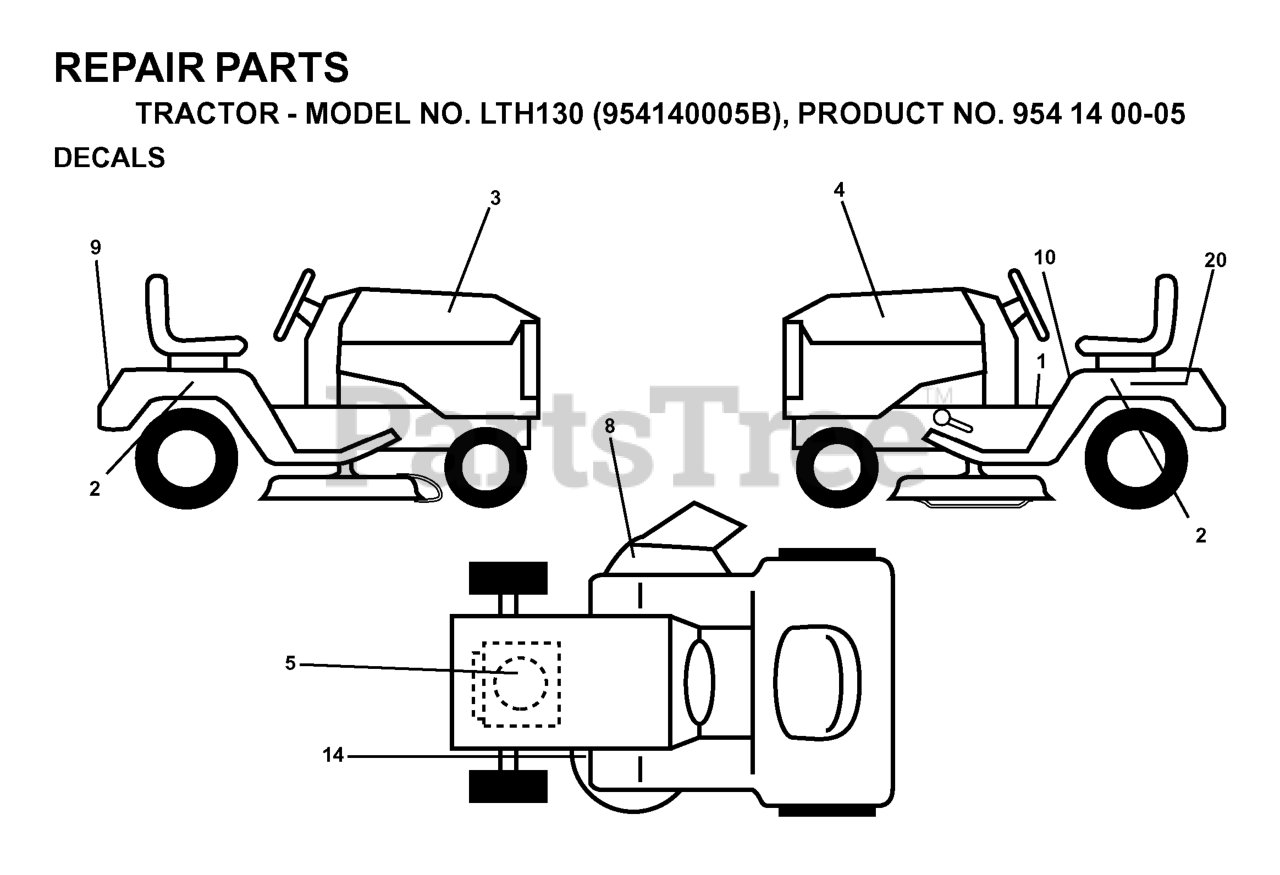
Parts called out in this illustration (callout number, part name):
3	DECAL HOOD RH
4	DECAL HOOD LH
8	DECAL WARNING (ENGLISH/FRENCH)
9	DECAL FENDER HUSQ
10	DECAL FENDER DANGER
14	DECAL V BELT SCHEMATIC
20	DECAL BTRY SYMBOLS
